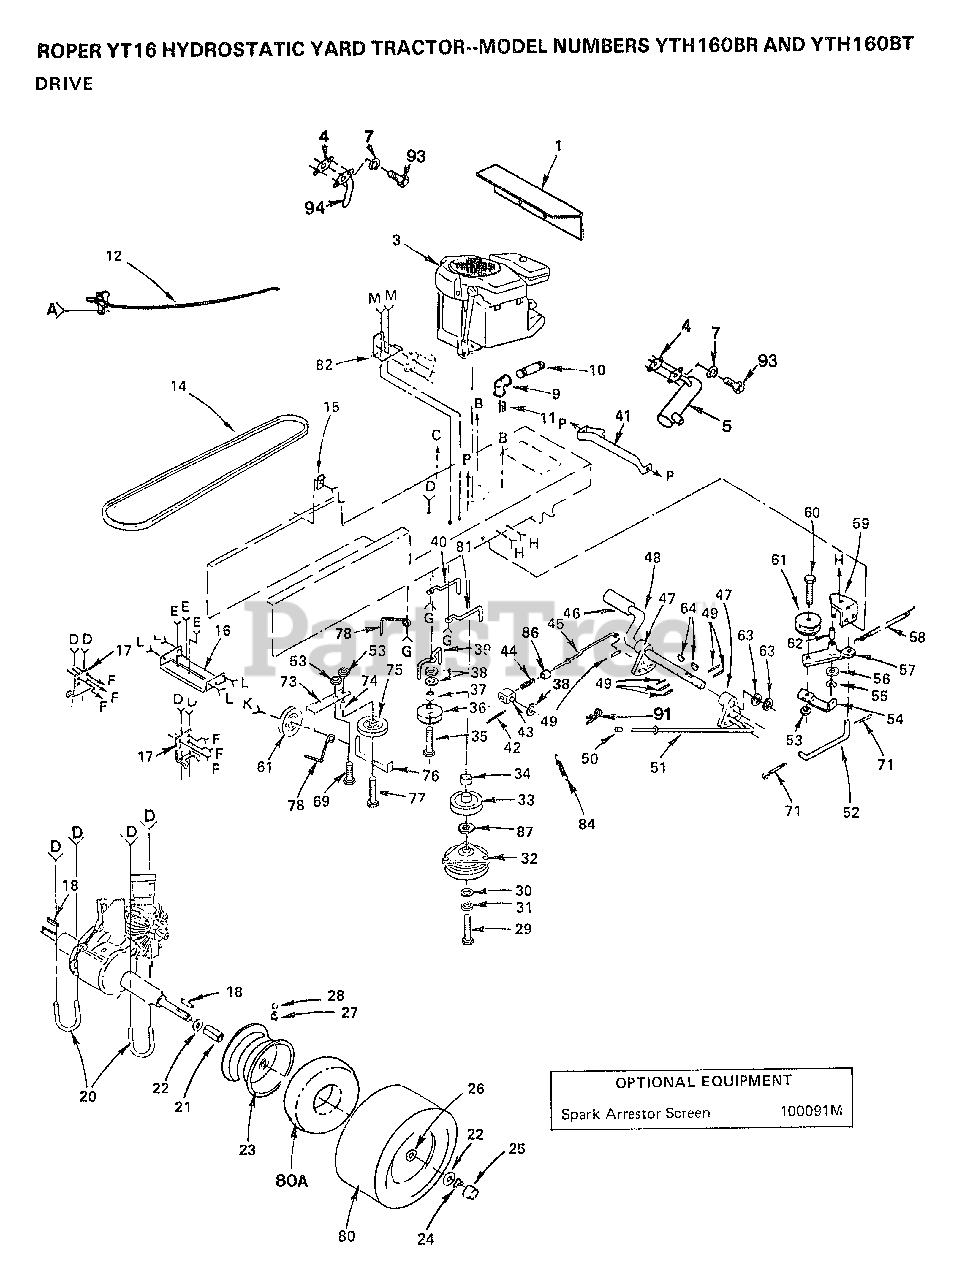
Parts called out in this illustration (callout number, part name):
1	BAFFLE - VERTICAL
2	SNAP BUSHING T
3	ENGINE, B&S
7	LOCKWASHER
9	ELBOW
10	PIPE NIPPLE LT
11	PLUG OIL DRAIN
12	THROTTLE CONTROL
15	CLIP T
17	BRKT, TRANSAXLE
18	SQ KEY STD
21	SPACER HYT
22	WASHER
24	E RING HYT
25	HUB CAP
27	VALVE STEM LT
28	VALVE CAP
30	WASHER T
31	LOCKWASHER
33	PULLEY ENGINE HYT
35	BOLT
37	SPACER T
38	WASHER
39	BELT KEEPER LT
42	COTTER PIN
43	TRUNION HYT
44	SPRING BRAKE HYT
46	PEDAL COVER T
47	ARM BRAKE LT
48	SHAFT, FOOT PEDAL
50	PLUNGER CAP T
52	"LINK, CLUTCH T"
55	KLIP RING
56	WASHER T
58	"SPRING, RETURN LT"
62	"LY, BEARING"
69	BOLT
71	COTTER PIN
73	BRKT IDLER HYT
74	SPACER SPLIT LTV
75	IDLER.PULLEY.LT
76	KEEPER BELT HYT
77	BOLT - HEX 3/8 - 16 X 3
78	BELT RETAINER GT
80A	TUBE.18X9.5-8
82	BRACKET LT
84	SPRING-EXT LT
87	WASHER T
94	EXHAUST TUBE T
